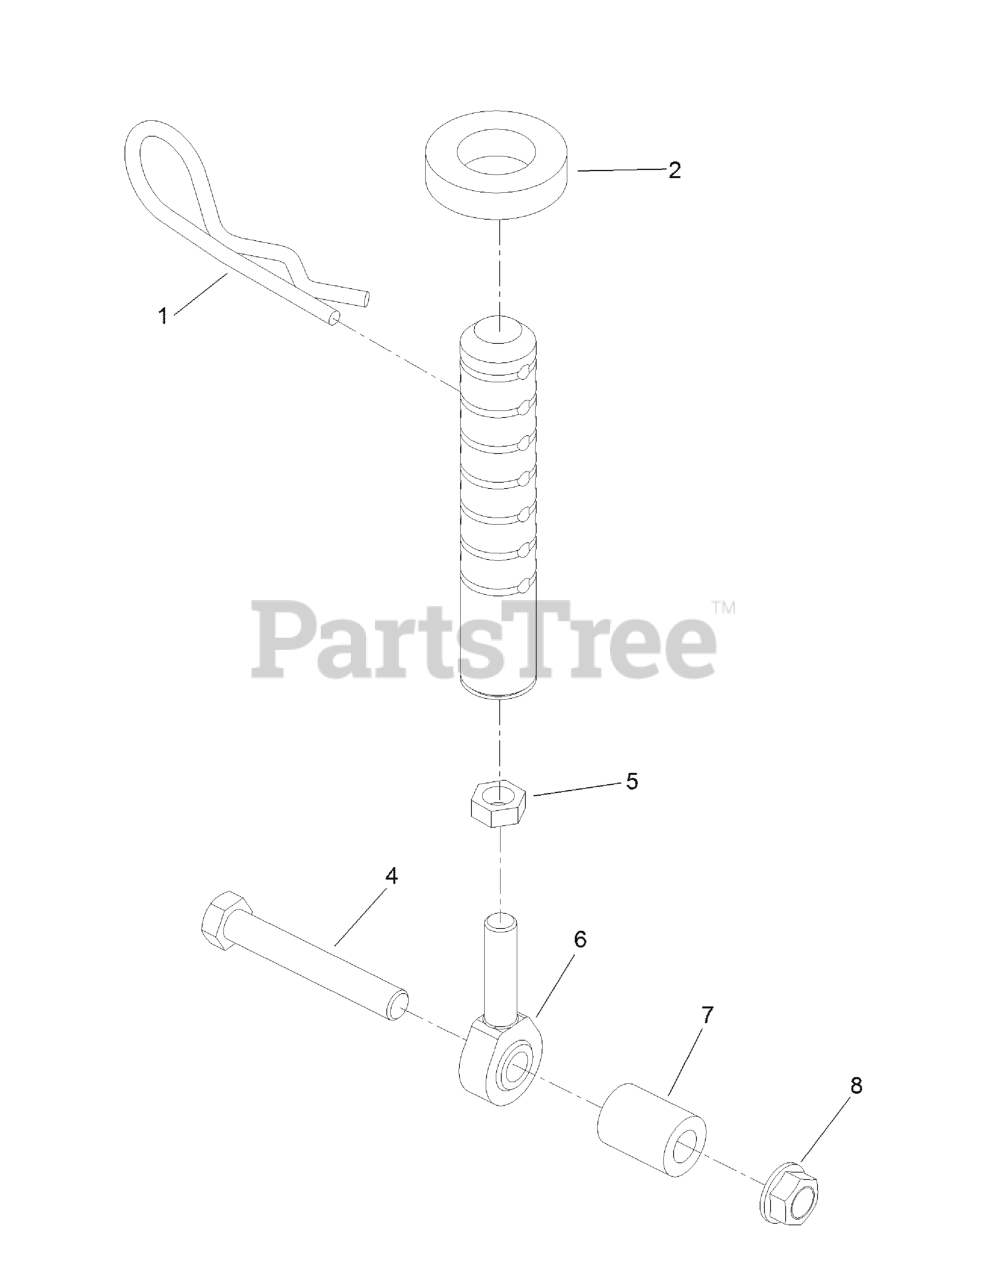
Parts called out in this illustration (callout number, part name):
1	PIN-CUT HEIGHT
2	SPACER-DECK SUPPORT
4	SCREW-HH
5	NUT-HJ
6	BALLJOINT
7	TUBE-INTERLOCK
8	NUT-HHF, WHIZ
